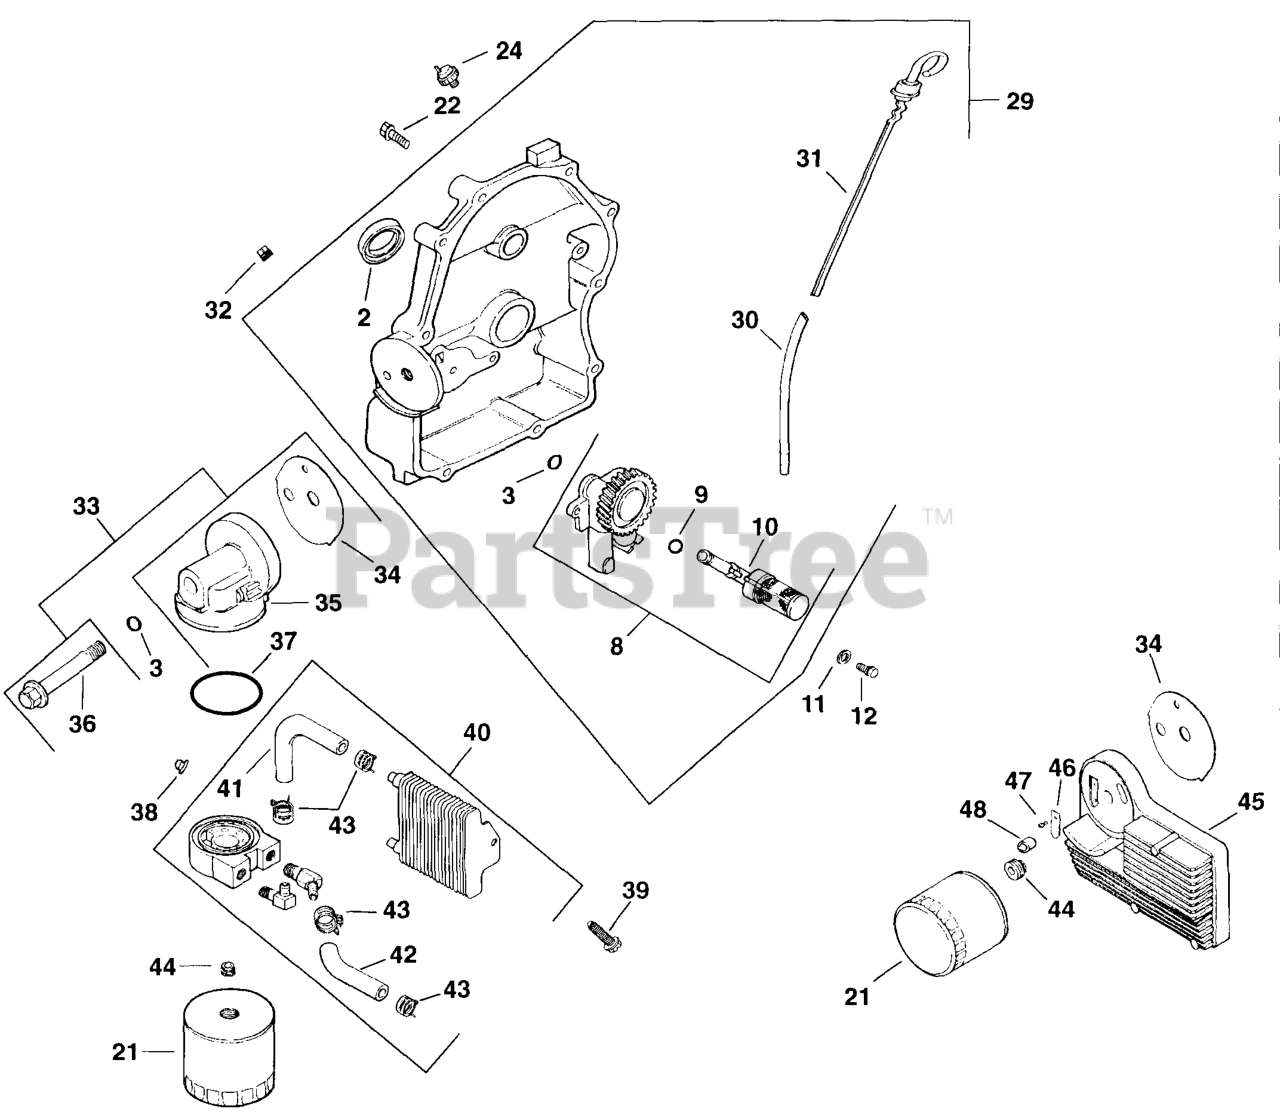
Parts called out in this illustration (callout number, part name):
2	SEAL, OIL (KM)-USE 25 032 06-S
8	PUMP, OIL - DISCONTINUED
9	O-RING, OIL PICK-UP
10	PICK-UP, OIL - DISCONTINUED
10	PICK-UP, OIL
11	WASHER - USE M-631005
12	SCREW - USE M-645025
21	OIL FILTER
22	SCREW, HEX FLANGE -USE 24 086 17-S
24	SWITCH - USE 25 099 24
34	GASKET - USE 24 041 29
46	REED, OIL RELIEF - DISCONTINUED
47	Screw, hex. cap M4x0.7x10
48	PIN - USE 12 380 17
